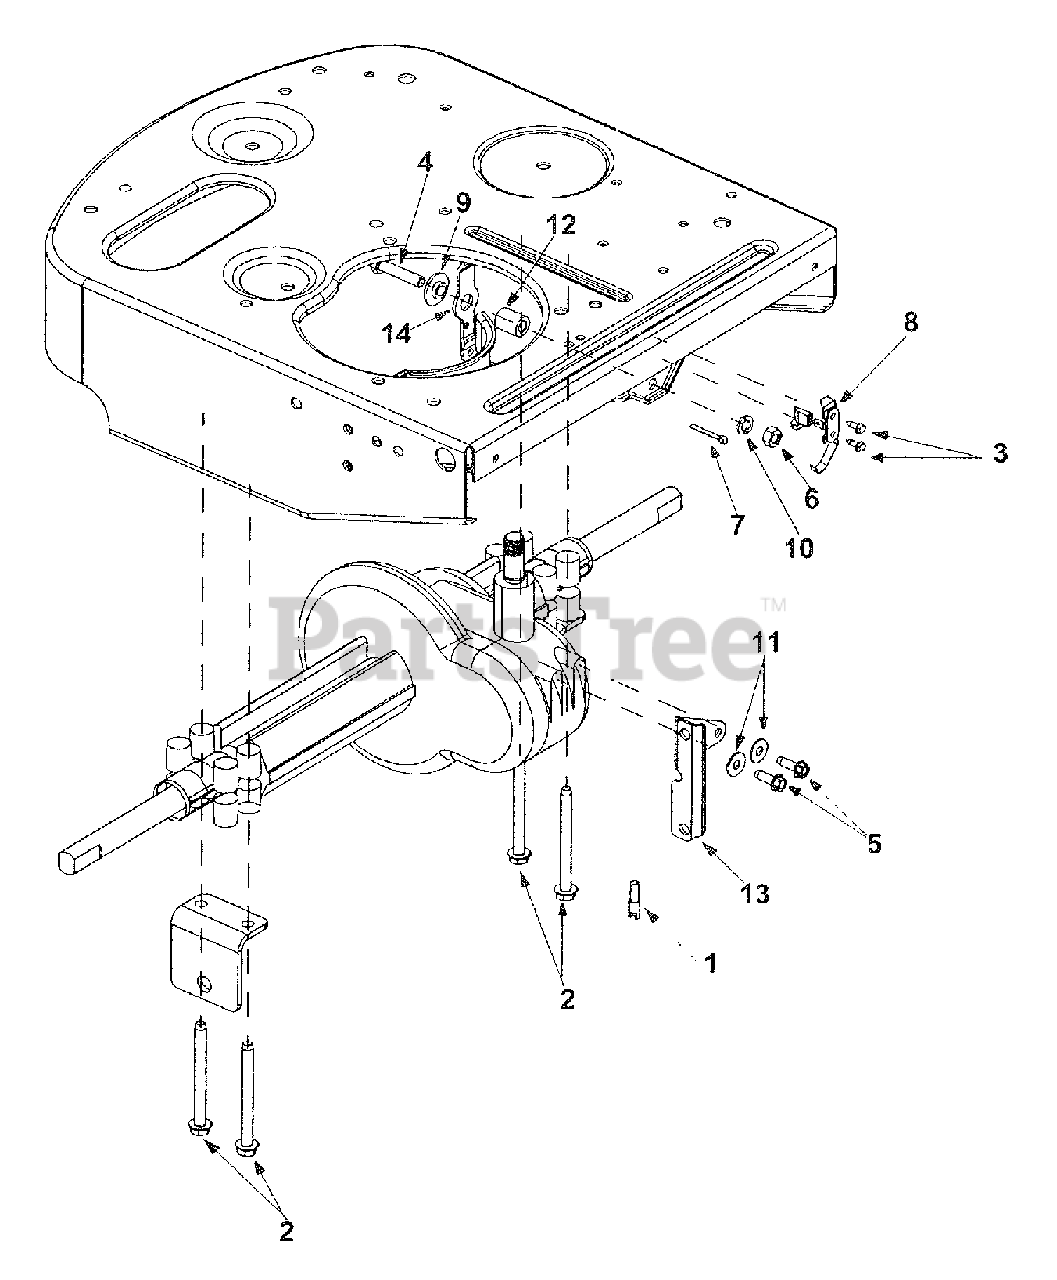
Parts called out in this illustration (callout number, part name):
1	Harness Assembly Adapter
2	Hex TT Screw 5/16-18 x 3.50
3	Hex Washer Head Self-Tap. Scew
4	Hex Screw 5/16-18 x 1.5 Gr. 5
5	Thd. Forming Scr. 1/4-20 x .75
6	Hex Nut 5/16-18
7	Cotter Pin
8	Insulator Nut Plate
9	Shoulder Bushing
10	Lock Washer 5/16
11	Flat Washer .28 I.D. x .74 O.D. x .083
12	Spacer
13	Transaxle Bracket
14	Shift Lever
